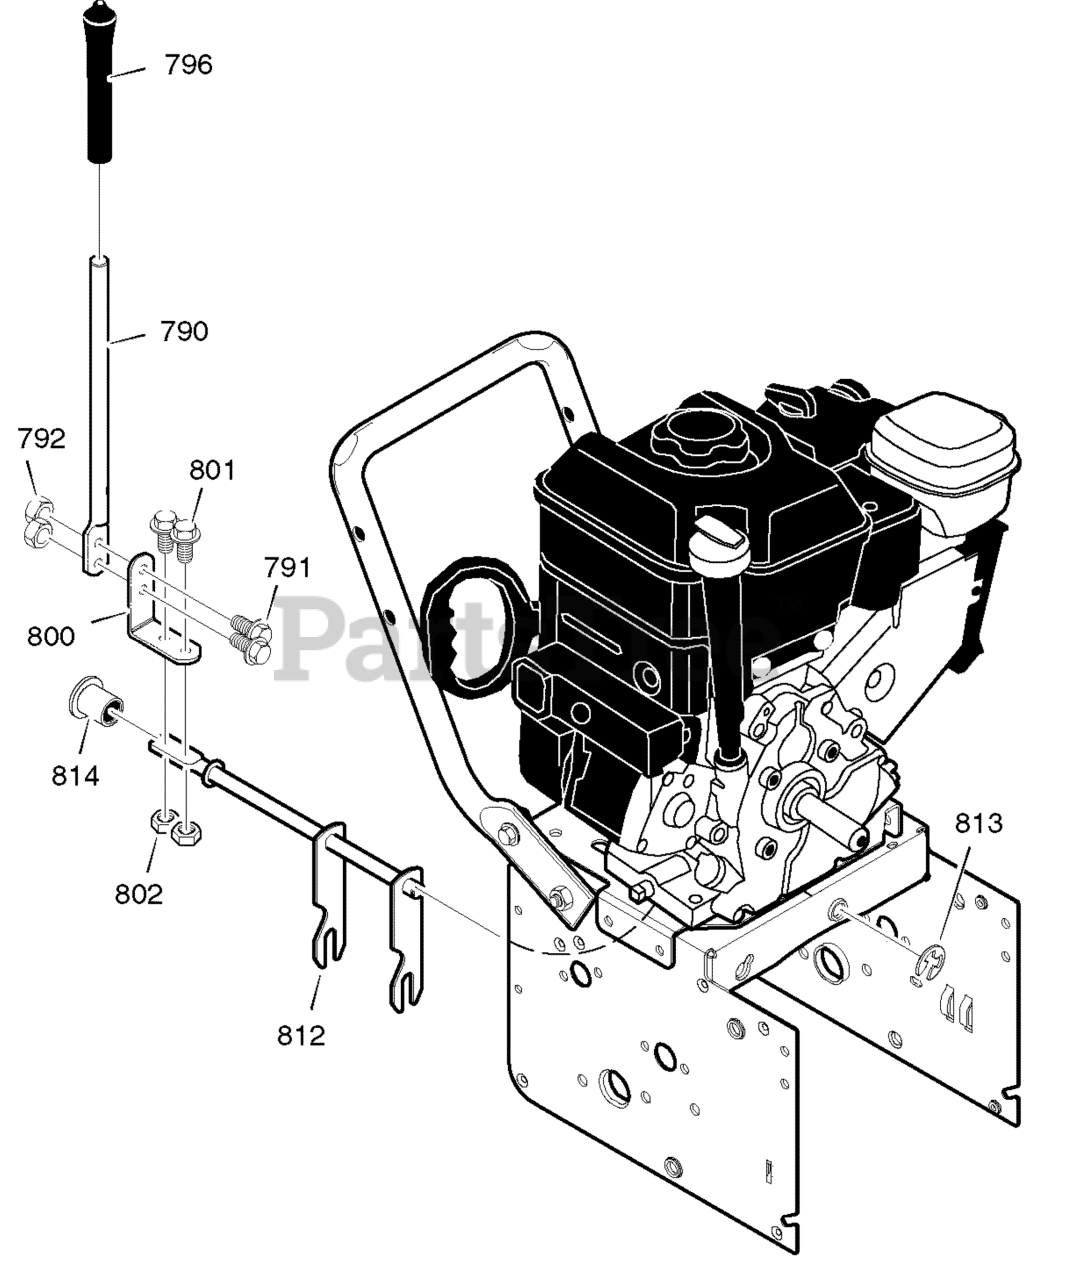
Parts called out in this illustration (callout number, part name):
790	ROD, SHIFT
791	SCREW, 1/4-20X.75
792	NUT, 1/4-20
796	KNOB, SLIP
800	LEVER, SPRING
801	SCREW, 1/4-20X.75
802	NUT, 1/4-20
812	ROD ASSY., SPEED SELECT
813	RETAINER, RING
814	BEARING, FLANGED
